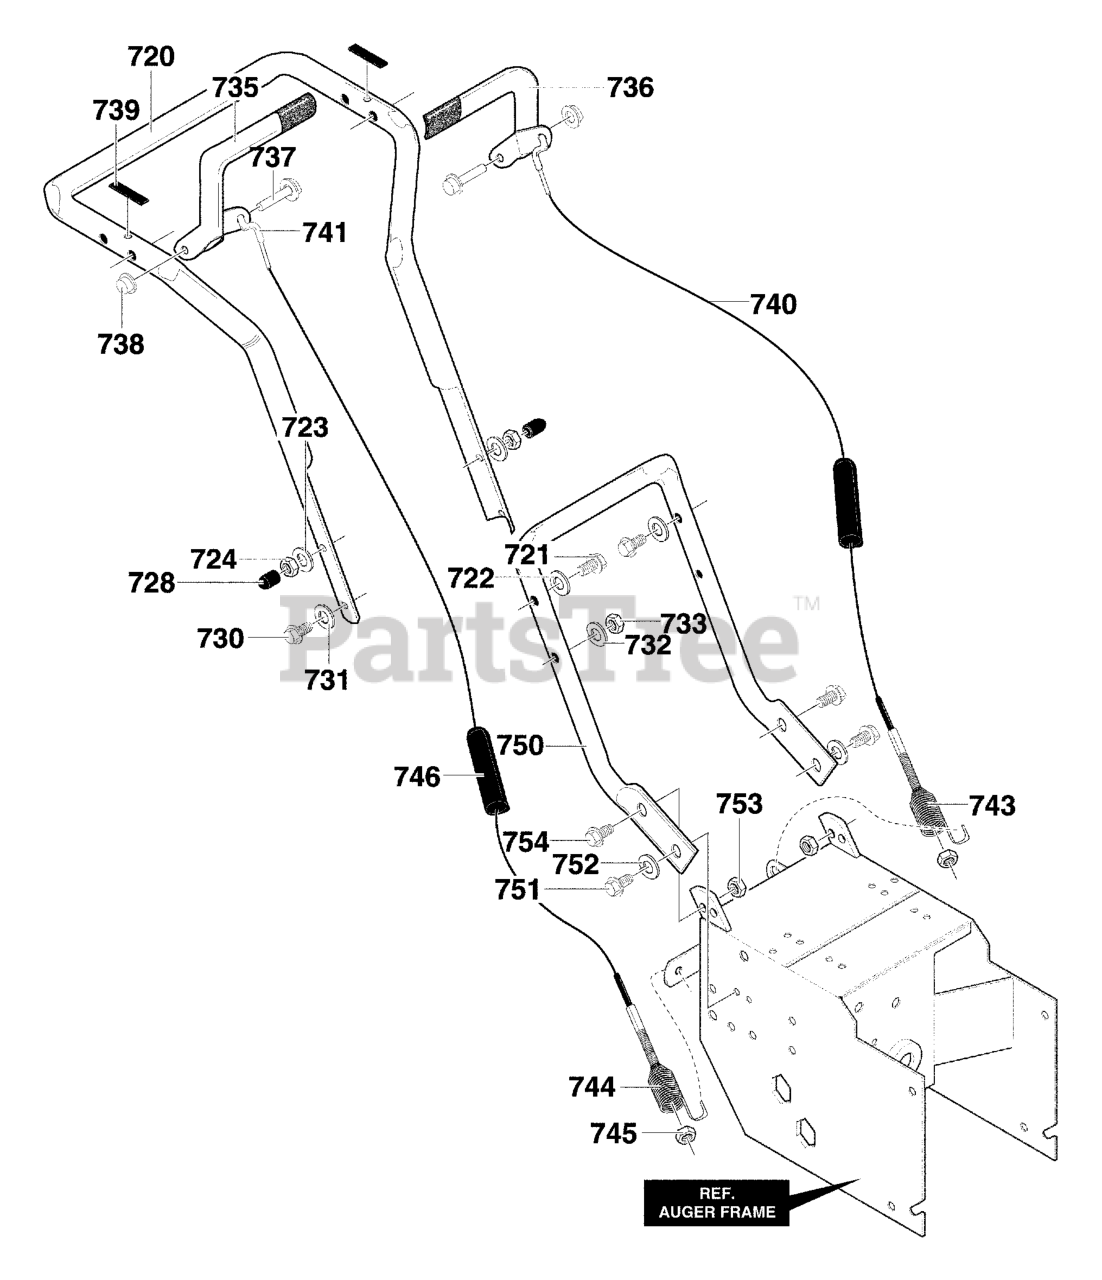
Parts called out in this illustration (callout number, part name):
720	HANDLE, UPPER LOOP
721	SCREW, 3/8-16 x 3.00
722	WASHER, FLAT
723	WASHER
724	NUT, 3/8-16
728	STOP, PLASTIC
730	SCREW, 3/8-16 x 2.00
731	WASHER, FLAT
733	NUT, 3/8-16
735	HANDLE, RIGHT
736	HANDLE, LEFT
737	PIVOT CLUTCH PIN
738	PUSH ON CAP
739	BUMPER, RECTANGLE
740	CABLE, CLUTCH 28.44L
741	CABLE, AUGER CLUTCH 25.5
743	TENSION SPRING
744	SPRING, AUGER CLUTCH
745	NUT, 1/4-20
746	BOOT, CLUTCH SPRING
750	HANDLE, LOWER
751	SCREW, 5/16-18 x 0.75
752	WASHER
753	NUT, 5/16-18
754	SCREW, 5/16-18 x 0.75
